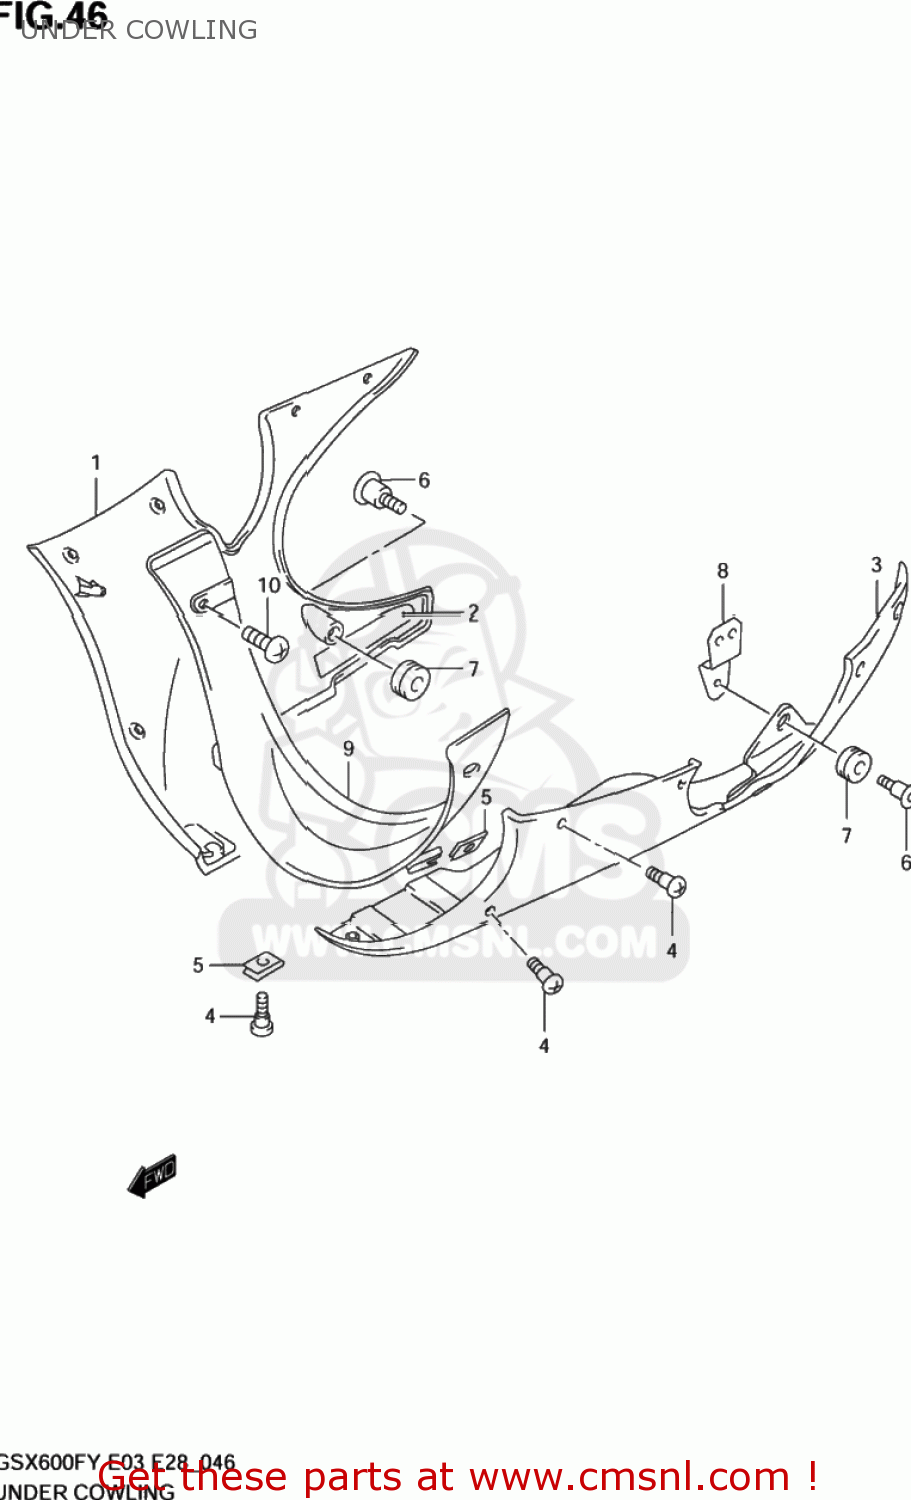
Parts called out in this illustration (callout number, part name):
1	COWLING,UNDER,R(GRAY)
2	SHIELD,COWLING UNDER,R NO.1
3	COWLING,UNDER,L
4	SCREW(5X16)
5	NUT,COWL
6	SCREW(6X20)
7	CUSHION
8	BRACKET,UNDER COWL,L & FRAME
9	COWLING,UNDER CTR
10	SCREW
